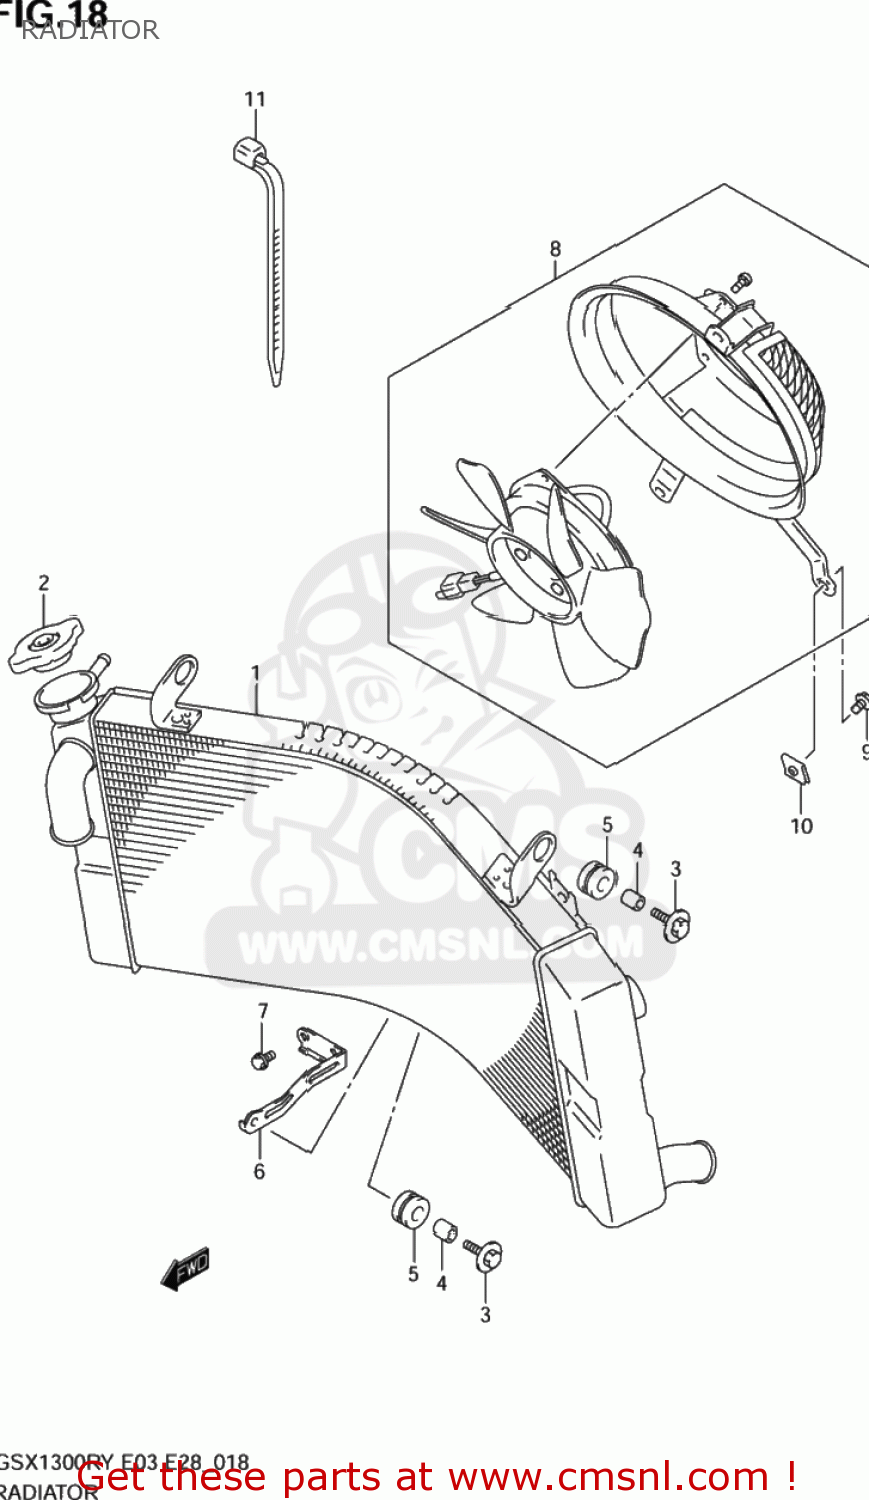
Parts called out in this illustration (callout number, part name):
1	RADIATOR ASSY,WATER
2	CAP COMP,RADIATOR
3	BOLT(6X25)
4	SPACER(6.5X10X12)
5	CUSHION
6	BRACKET,RADIATOR
7	BOLT
8	FAN ASSY,RADIATOR
9	BOLT
10	NUT
11	CLAMP(L:165)
